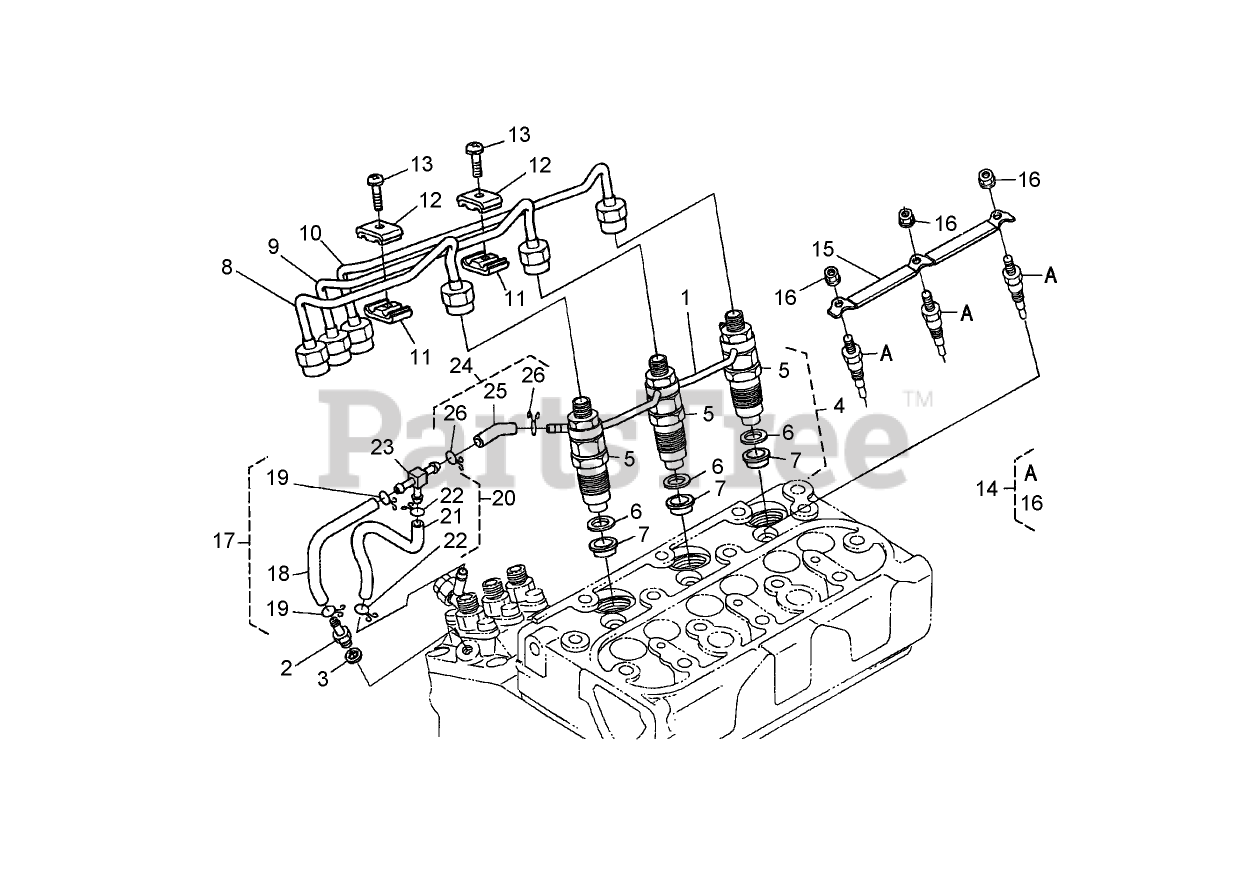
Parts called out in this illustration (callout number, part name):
1	OVER FLOW PIPE ASM
2	SCREW-BLEEDER, AIR
3	GASKET
4	NOZZLE HOLDER KIT
5	NOZZLE HOLDER ASM
6	GASKET
7	SEAL-HEAT
8	PIPE-INJECTION
9	PIPE-INJECTION
10	PIPE-INJECTION
11	CLAMP-PIPE
12	CLAMP-PIPE
13	SCREW (W/WASHER)
14	PLUG-GLOW
15	CORD-PLUG, GLOW
16	NUT-FLANGE
17	FUEL TUBE ASM
18	TUBE-FUEL
19	CLIP-PIPE
20	FUEL TUBE ASM
21	TUBE-FUEL
22	CLIP-PIPE
23	JOINT-T PIPE
24	FUEL TUBE ASM
25	TUBE-FUEL
26	BAND-PIPE
